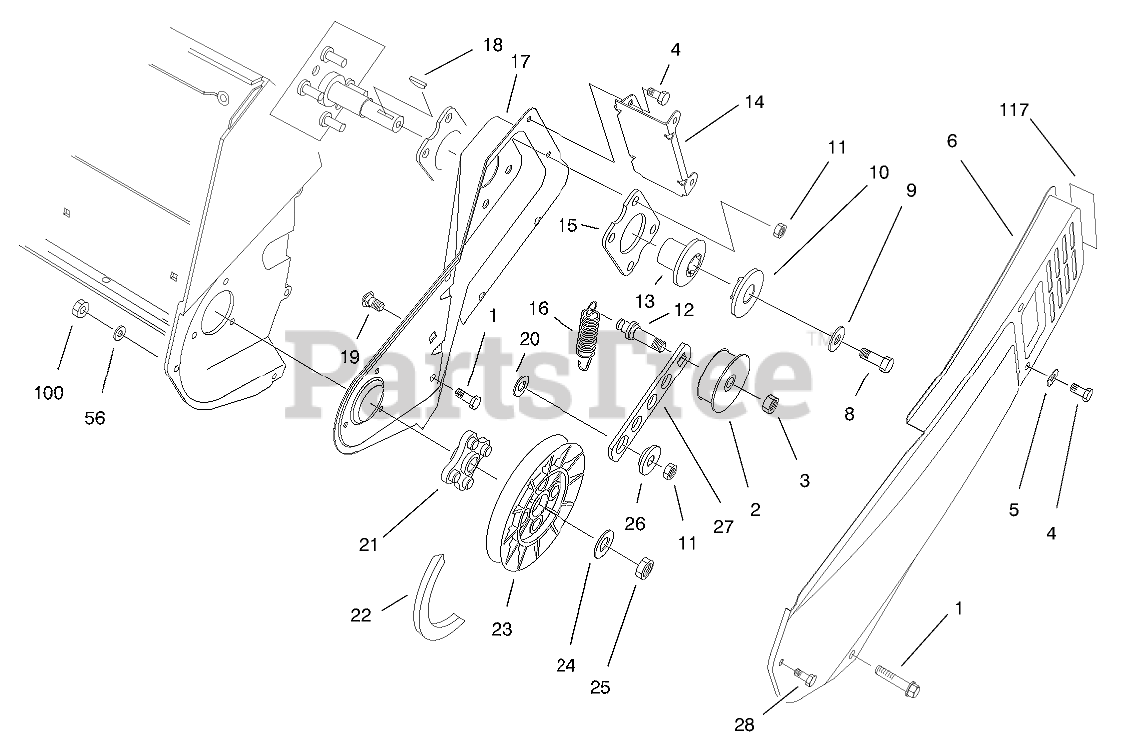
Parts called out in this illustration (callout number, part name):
1	SCREW-PLASTIC
2	PULLEY-IDLER
3	NUT-LOCK, NI
4	SCREW-HWH
5	WASHER-FLAT
6	Cover-Belt
8	SCREW-HH
9	WASHER-FLAT
10	CAP-HALF SHEAVE
11	NUT-LOCK, NI
12	PIN-IDLER
13	Hub-HALF SHEAVE
14	Bracket-Cover
15	Plate Engine
16	SPRING-EXTENSION
17	Sideplate-LH
18	KEY-WOODRUFF
19	SCREW-CARR
20	WASHER
22	V-BELT
23	PULLEY-DRIVEN
24	WASHER-FLAT
25	NUT-LOCK, NI
26	BUSHING-IDLER
27	ARM-IDLER
56	WASHER-FLAT
100	NUT-LOCK, NI
117	DECAL-HOT
